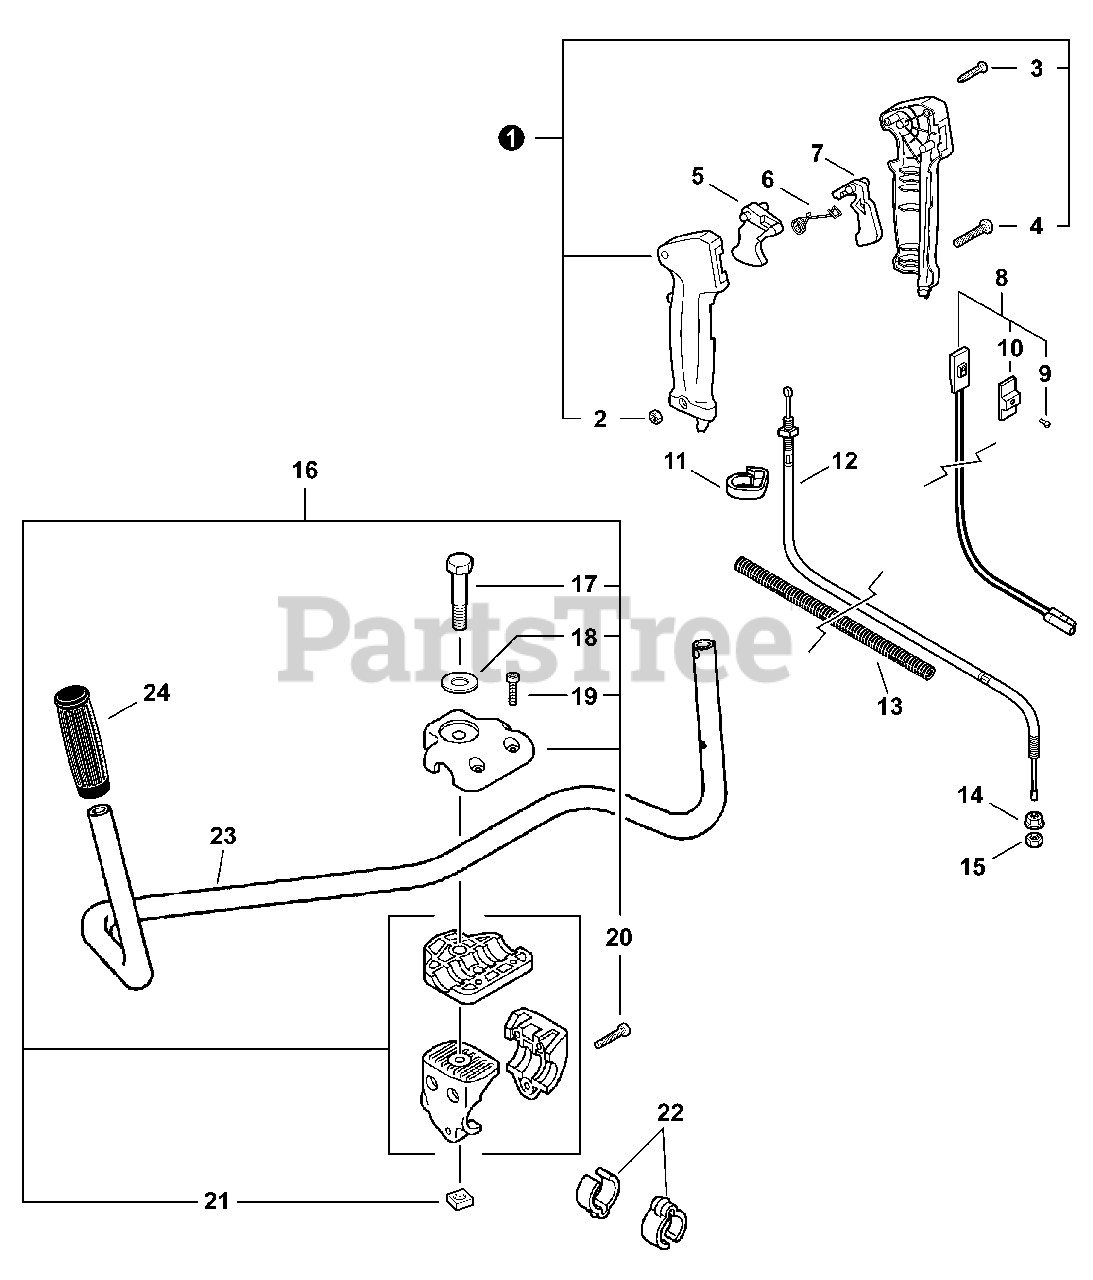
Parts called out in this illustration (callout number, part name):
1	CONTROL HANDLE KIT
2	NUT M5
3	SCREW 3×25
4	SCREW 5×30
5	TRIGGER, THROTTLE
6	SPRING, TORSION
7	LOCKOUT, THROTTLE
8	SWITCH, ON-OFF
9	SCREW 3×10
10	KNOB, SWITCH - ORANGE
12	CABLE, THROTTLE
13	TUBE, FLEXIBLE 7×790
14	NUT, FLANGE M6
16	HANDLE BRACKET KIT
17	BOLT 8×55
18	WASHER 8
19	BOLT, TORX 5×20
20	BOLT, TORX 5×25
21	NUT 8×1.25
22	CLIP, CABLE 25 MM
23	HANDLEBAR
24	GRIP, HANDLE
